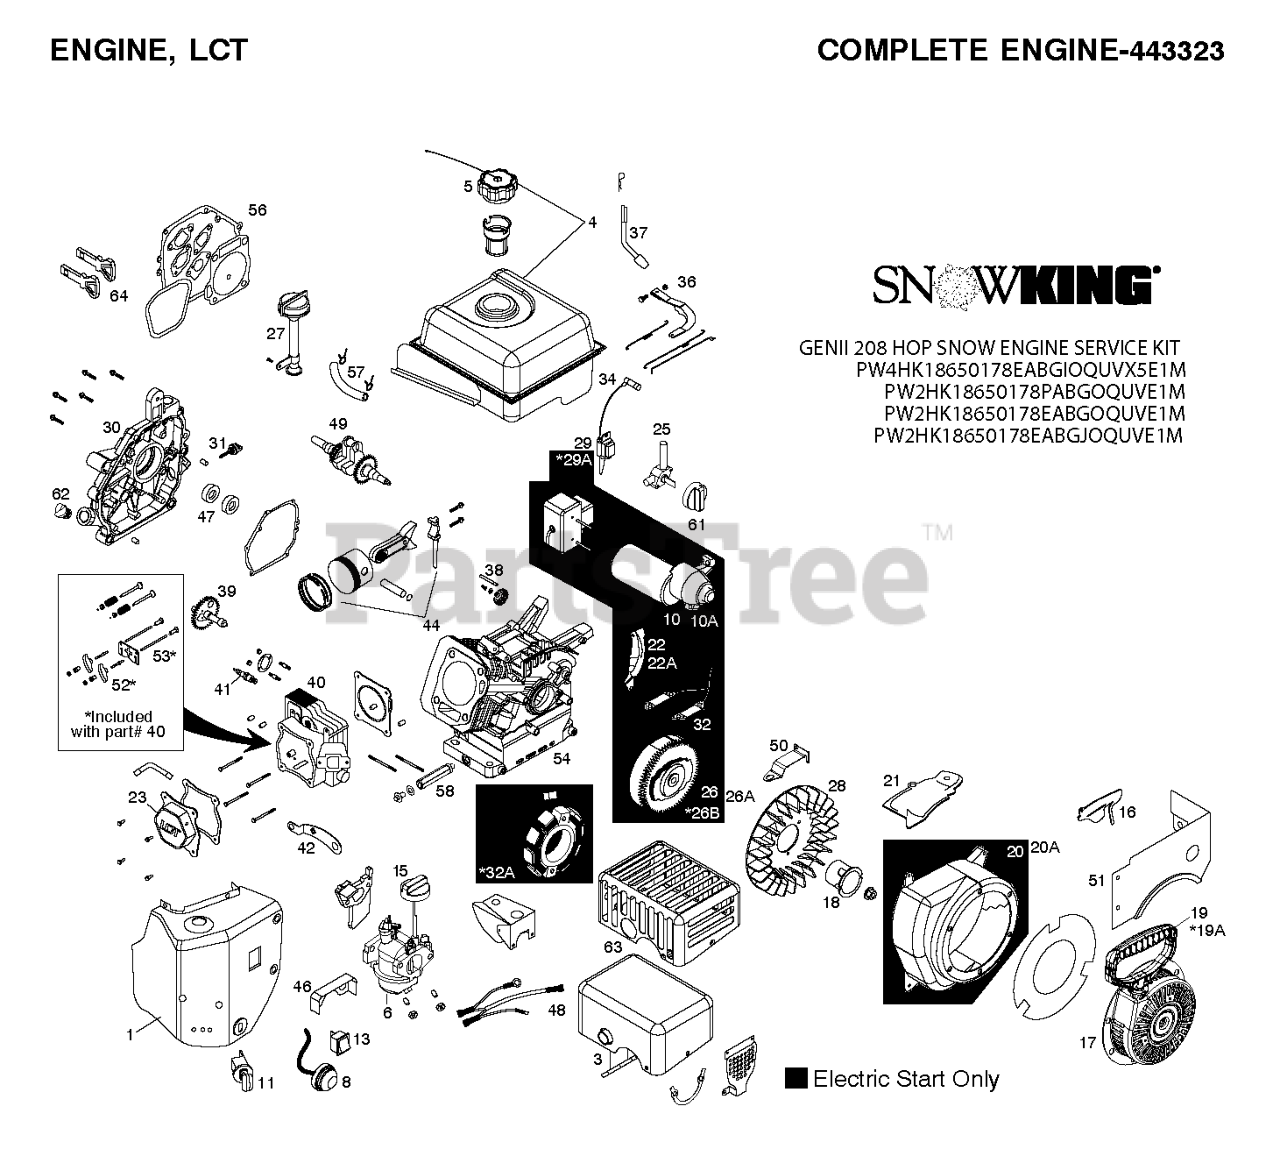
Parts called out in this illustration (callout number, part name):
1	HEATER.BOX.ASY-GEN2
3	ASSY.MUFFLER.GENII.SKSN0201.1
4	FUEL.TK.ASSY.GENII.SKSN0311.1
5	FUEL CAP OVERSIZED CLICK STYLE
6	CARB.ASSEMBLY.GEN.II.LCT.208CC
8	PRIMER.BULB.WITH HOSE (SNOW)
10	ELEC.START.GEN2.SKSN0451.1
10A	STARTER.EL.230C.SNO.LCT.208CC.
11	SWITH.KEY.ASSEM.SNOW.SINGLE.ST
13	SWITCH.ON/OFF(SKSN-0403)
15	CHOKE.KNOW.SNOW(SKSN4500)
16	GOVERNOR.LINK.SHIELD PLATE
17	RECOIL.STRT.ROUND(BLK) SNOW
18	STRTER.CUP(NON-SLOT)SKSN0601.2
19	STARTER.GRIP.SNOW.LCT.SKSN0603
19A	HANDLE.RECOIL.DELUXE.LCT
20	BLOW.HSG.ASSY.ELEC(SKSN-0602)
20A	BLOW.HSG.ASSY.ELEC(SKSN-0612)
21	SHILED.FLYWEEL.SYS(SKSN-0604)
22	SHLD.ELEC.START.FLY(SKSN-0605)
22A	SHIELD.FLYWEEL.MAN(SKSN-0607)
23	VALVE COVER ASSEMBLY
25	FUEL.PETCOCK.SNOW(SKSN4900)
26	FLYWHL.ASSY.ELECT.(SKSN0405)
26A	RP KIT.FLYWHEEL.SERVICE
26B	208CC ELEC START FLYWHEEL
27	HIGH OIL FILL DIPSTICK ASSEM
28	FLYWHEEL FAN 420586
29	208CC IGN COIL (STD)
29A	COIL.ING.CDI.HI TEMP.SKSNO416.
30	CRANKCASE COVER ASSY
31	DIPSTICK SMALL
32	CHARGING.COIL(ELEC)SKSN0406.1
32A	208CC 60W ALTERNATOR
34	SPARK.PLUG.BOOT.SNW,SKSN4691.1
36	RP_IT.GOVERNOR.ARM(SUMMER ENG)
37	KIT.GOVERNOR.CRANK(SK208-3100)
38	GOVENOR.GEARS ASM(SK2082900)
39	KIT.CAMSHAFT.208CC.LCT
40	CYLINDR.HEAD.SRV.KIT W/GASKET
41	SPARK.PLUG(2083810)
42	CDI.BOX.BRACKET SNOW
44	KIT.PISTON.SRV(SK208-1400)
46	SHIELD.VAPOR.SNOW
47	SEAL KIT (2 PCS)
48	WIRE.HARNESS.SNOW
49	CRANKSHAFT-KEYED(SK2081800.1)
50	SPEED.CTRL.BRKT.(SKSN0150)
51	FUEL.TNK.SKRT.GENII.SKSN0103.1
52	ROCKER ARM KIT
53	KIT.PUSH.ROD.SRV(SK208-1001)
54	CYLINDER.ASM.SKSN0001.2
56	GASKET.KIT.208CC(SK2084300.1)
57	FUEL HOSE KIT
58	EXTENDED OIL DRAIN TUBE
61	FUEL KNOB-SNOW
62	NON REMOVABLE PLUG
63	SHIELD.MUFFLER.CE.COMPLIANT
64	KEY SET(2 KEYS) SKSN0407.1
